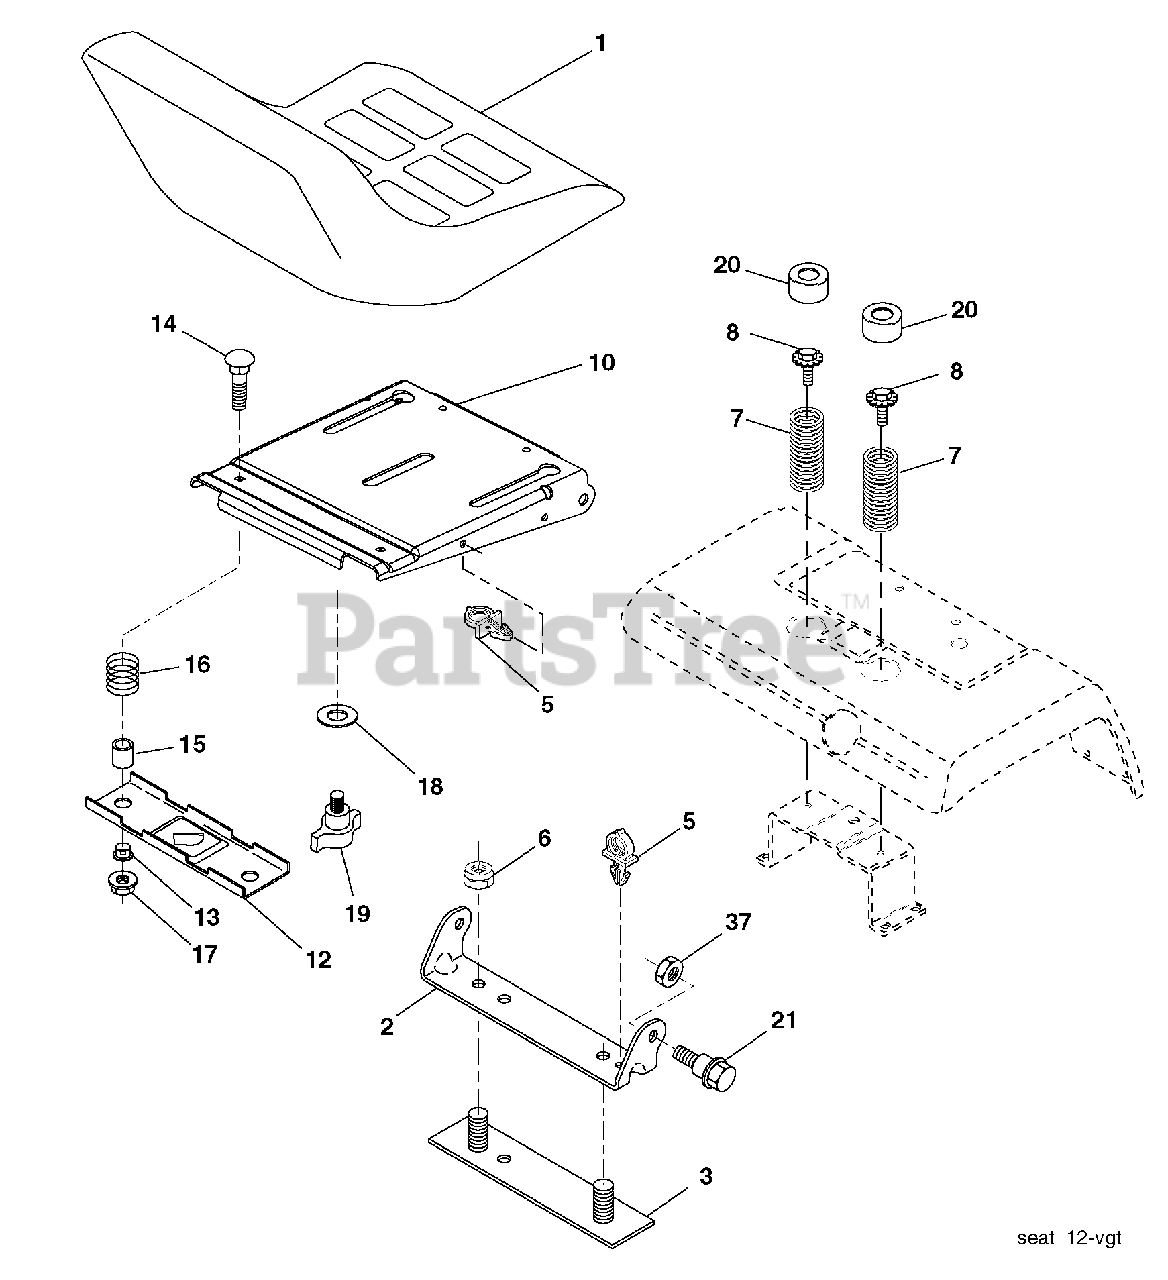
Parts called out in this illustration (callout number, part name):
1	Seat
2	Bracket, Pivot Seat
3	Strap Asm.
5	Clip, Push-In Hinged
6	Nut, Crownlock 3/8-16
7	Spring, Seat Cprsn.
8	Bolt 5/16-18 unc x 3/4 w/Sems
10	Pan, Seat
12	Bracket, Mounting Switch
13	Bushing, Snap
14	Bolt, Carriage 1/4-20 x 1-1/2
15	Spacer, Split
16	Spring, Cprsn.
17	Nut, Lock 1/4 Lg. Flg. Gr. 5
18	Washer 17/32 x 1-3/16 x 12 Ga.
19	Knob, Seat
20	Cap, Spring Seat Blk
21	Bolt 5/16-18 unc-2A
37	Nut, Crownlock 5/16-18
